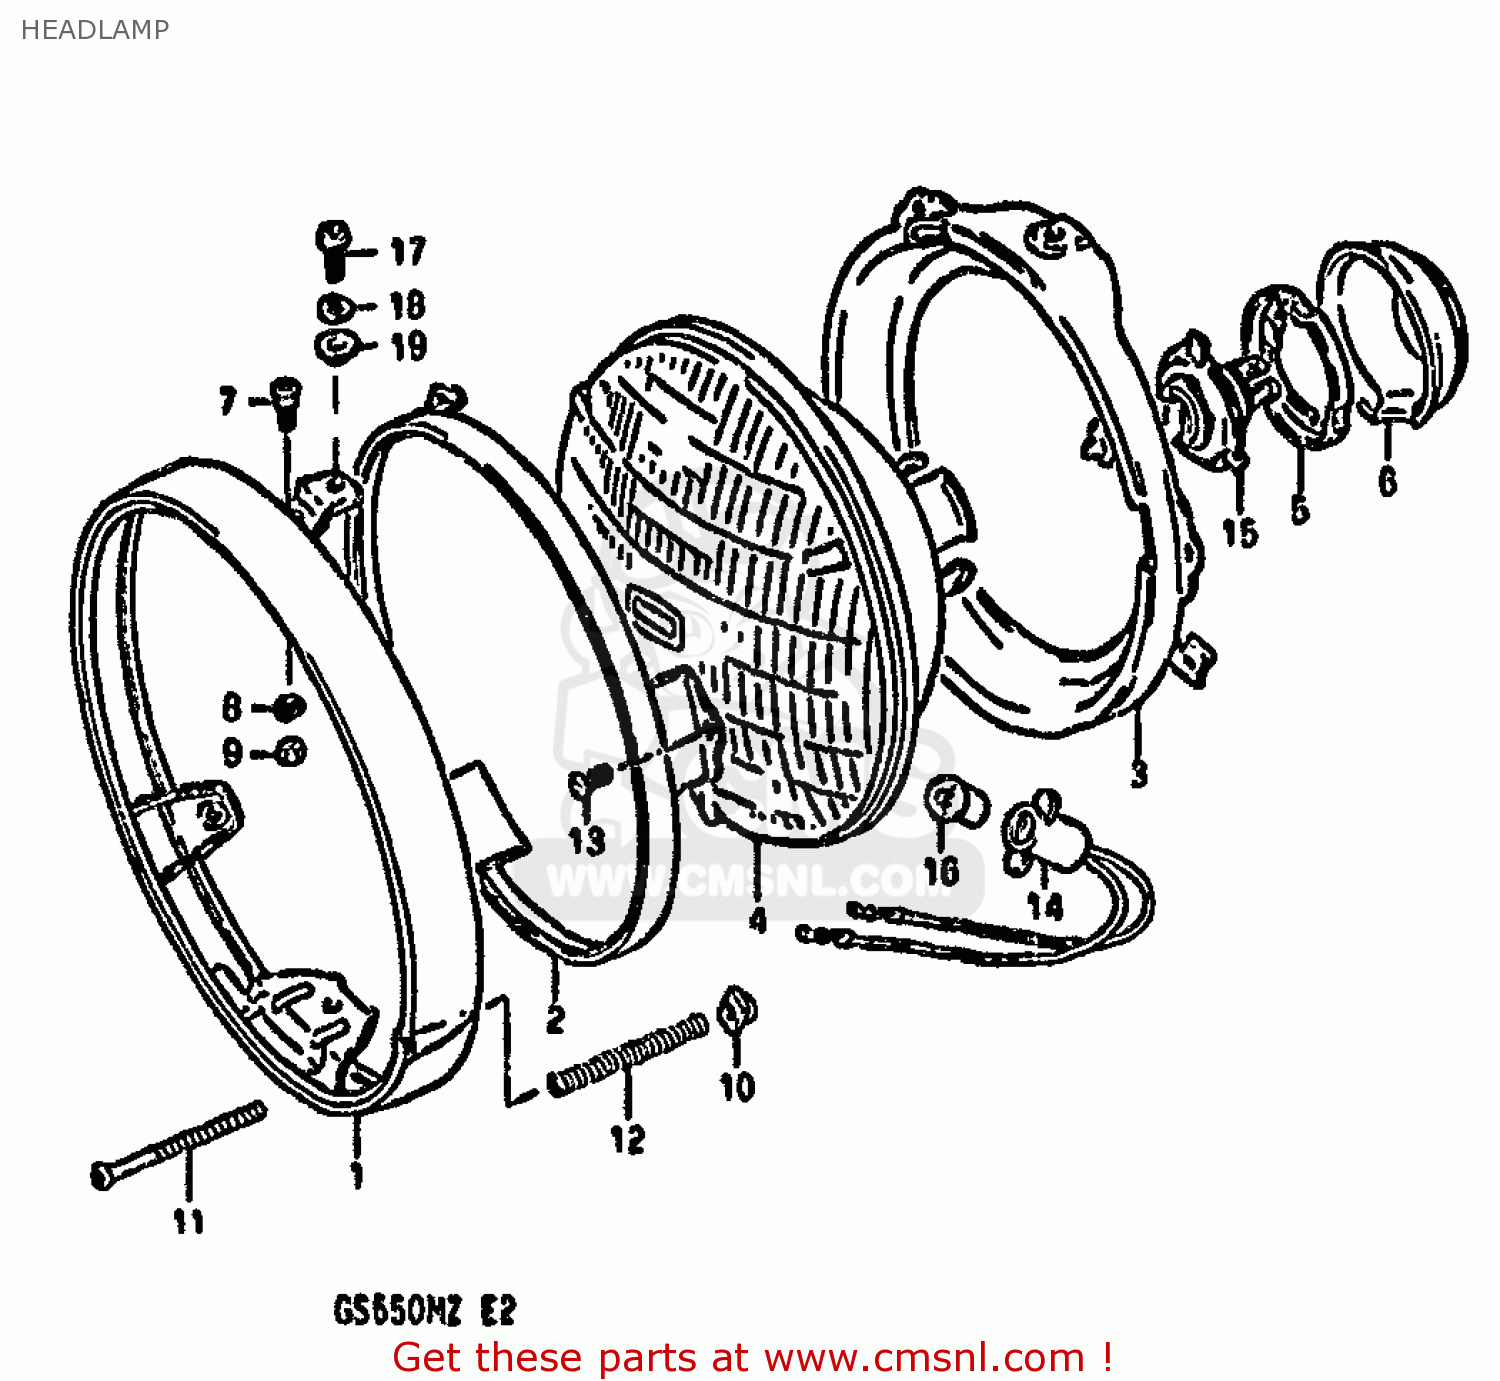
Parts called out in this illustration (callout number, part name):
1	RIM,HEADLAMP
2	RETAINING RING
3	RING
4	UNIT
5	SETTING,BULB
6	COVER,HEADLAMP SOCKET
7	H/LAMP LENS UNIT FITING SCRE
8	LOCK WASHER
9	NUT
10	NUT
11	SCREW,HEADLAMP ADJUST
12	SPRING,ADJUSTING
13	SCREW
14	SOCKET
15	BULB(12V60/55W,H4)
16	BULB
17	SCREW
18	WASHER,LOCK
19	WASHER
